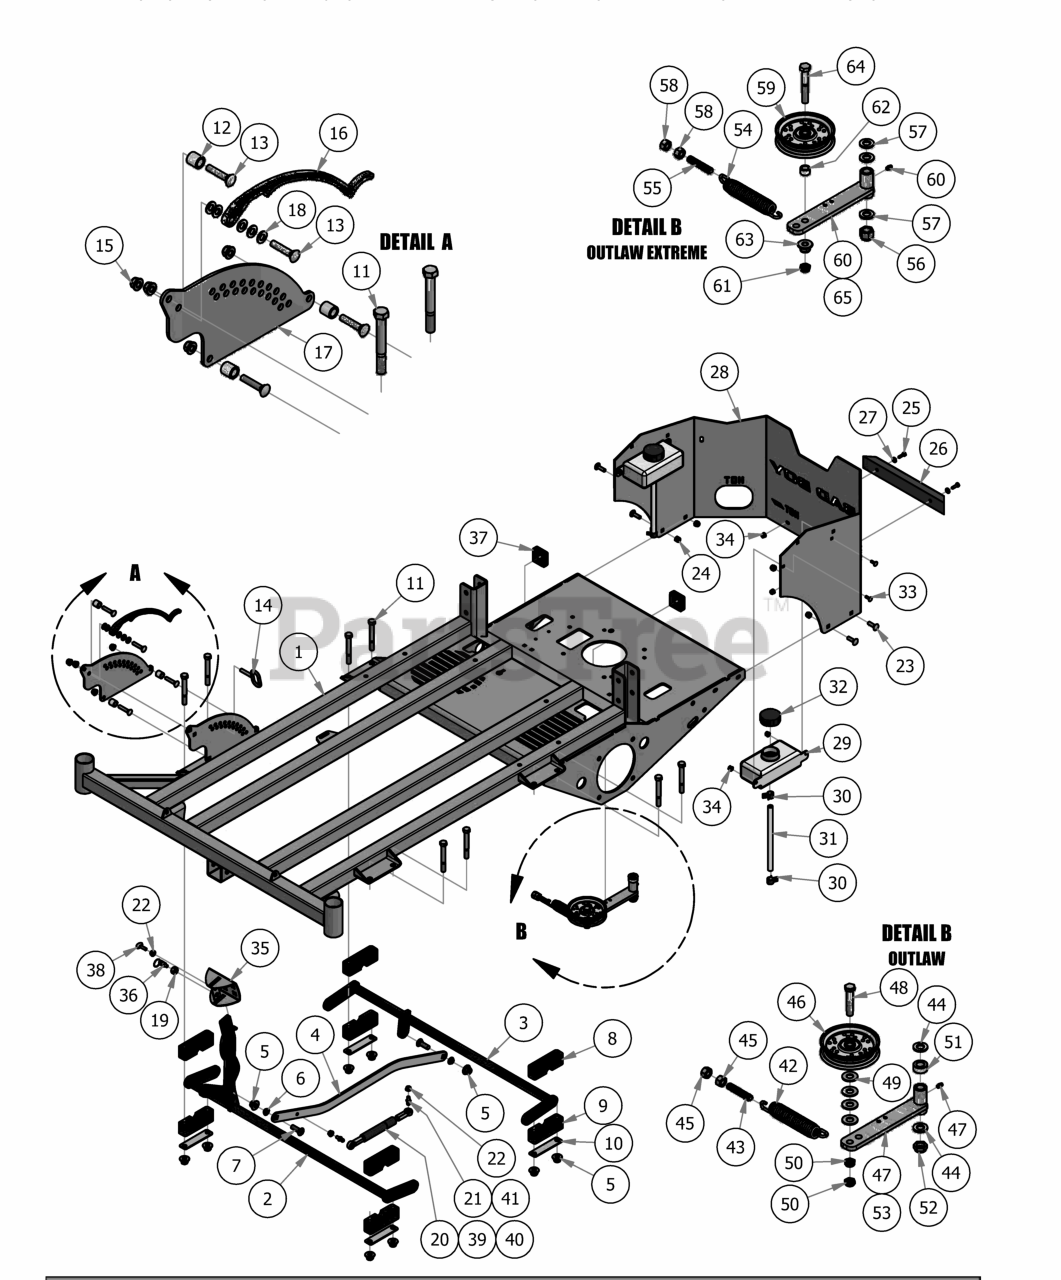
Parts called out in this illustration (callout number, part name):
1	2017 Standard/Extreme Outlaw Frame
2	2015 Outlaw Act Bar Assembly (Front)
3	2015 Outlaw Act Bar Assembly (Rear)
4	Outlaw Deck Linkage Rod
5	1/2-13 Nylon Flange Nut
6	Bushing- SF-1620-4
7	1/2 x 1-1/2 Carriage Bolt
8	Two Piece Pillow Block (Male)
9	Two Piece Pillow Block (Female)
10	Two Piece Pillow Block Strap
11	1/2" x 4" Bolt (Grade 8)
12	Spacer 3/4 OD x 1/2 ID x 3\4 Length
13	3/8 x 1 3/4 Carriage Bolt
14	Deck height lever pin
15	3/8" Nylock Flange Nut
16	Outlaw Deck Lever Lock
17	Outlaw Height Indicator Plate (Outer)
18	.390 x .750 x .062 Nylon Washer
19	1/2" Hex Nut
20	200 lb Gas Spring- 54" Deck outlaw
21	10mm Damper Ball Stud-Steering
22	5/16" Flange Nut
23	3/8" x 1 1/4" Carriage Bolt
24	3/8 Nylock Nut
25	1/4-20 x 1-1/4 GR 5 Hex Bolt
26	14" Rubber Bumper
27	1/4" Flat Washer
28	Outlaw Rear Plate
29	Expansion Tank Outlaw
30	5/8 Wire Clamp-Outlaw Only
31	5/8 Braided Hose
32	Hydraulic Tank Cap
33	1/4" x 3/4" Carriage Bolt
34	1/4-20 Nylon Insert flange Nut
35	Outlaw Deck Lift Pedal
37	2X2 Frame Plug
38	5/16-18 x1 Thumb Screw Zinc
39	250 lb Gas Spring - 61" Deck Outlaw
40	300 lb Gas Spring - 72" Deck Outlaw
41	13mm Damper Ball Stud for 72" Deck only
54	2009 Deck/Pump Idler Spring
55	All Thread-Pump Idler Tensioner
56	5/8 Std NC Nylock Nut
57	.630 ID Plastic Washer
58	1/2" Hex Nut
59	4 3/4 Idler Pulley - ABFI-76
60	Deck Idler
61	1/2" Nylcock Nut (1/2 Jam)
62	1/2 x 1/2 Spacer
63	1/2-13 Nylon Flange Nut
64	1/2 x 2-3/4 Hex Bolt
65	Pump Idler Assembly-Components:59,60,62,63,64
